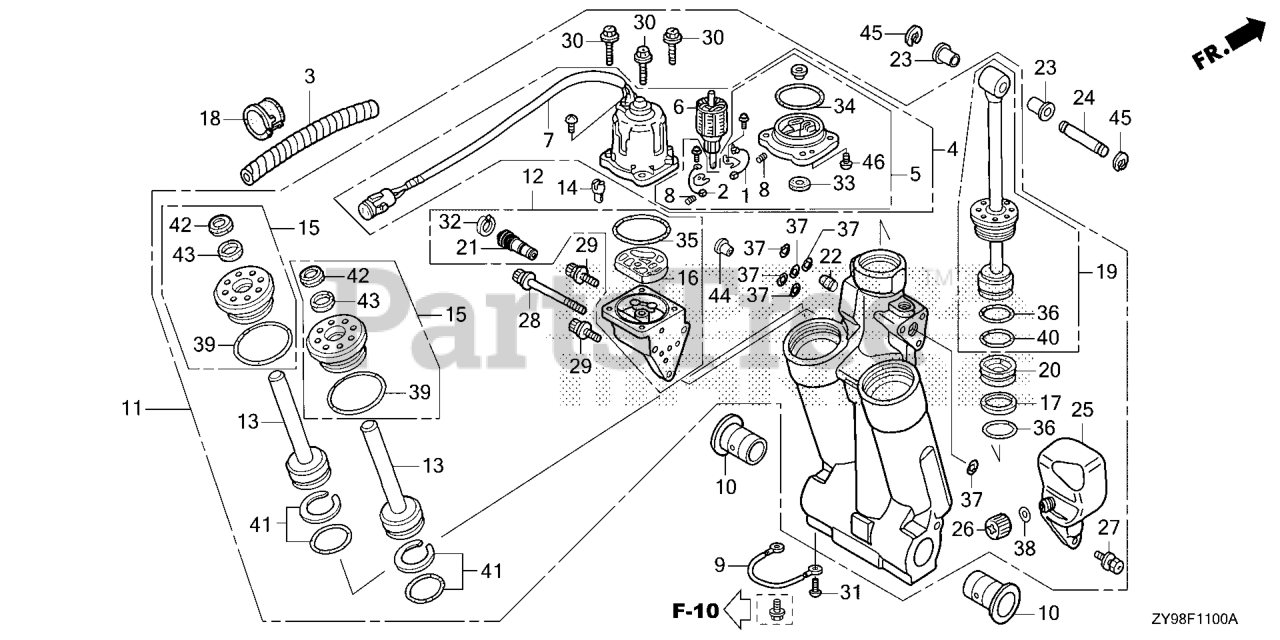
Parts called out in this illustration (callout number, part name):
1	BREAKER ASSY.
2	BRUSH ASSY.
3	TUBE, SPIRAL (12X14.6)
4	MOTOR ASSY., POWER TILT
4	MOTOR, POWER TILT
5	BRACKET ASSY.
6	ARMATURE
7	YOKE ASSY.
8	SPRING, MOTOR
9	WIRE, LEAD (1.5X116MM)
10	BUSH, SWIVEL CASE
11	TRIM/TILT, POWER
12	PUMP ASSY. (NOT AVAILABLE)
13	ROD, PISTON (B)
14	JOINT, DRIVE
15	GUIDE, ROD
16	FILTER (B)
17	RING, BACK-UP
18	BUSH, MOTOR CODE
19	ROD, PISTON
20	PISTON, FREE
21	VALVE, MANUAL (NOT AVAILABLE)
22	VALVE, RESERVOIR
23	BUSH, CYLINDER (LOWER)
24	PIN, CYLINDER (UPPER)
25	TANK, OIL
26	CAP, OIL TANK
27	BOLT, RECESSED
28	BOLT A, SOCKET
29	BOLT B, SOCKET
30	BOLT, HEX.
31	SCREW, PAN (6X8)
32	CIRCLIP (INNER)
34	O-RING (2.0X70.5)
35	O-RING (1.8X69.6)
36	O-RING (3.5X38.7)
37	O-RING (1.68X7.25)
38	O-RING (1.9X11)
39	O-RING (3.5X35.7)
40	O-RING (3.5X41.7)
41	O-RING SET (3.5X31.7)
42	SEAL, WATER
44	COLLAR, ORIFICE
45	E-RING (15MM)
46	SCREW (4X16)
